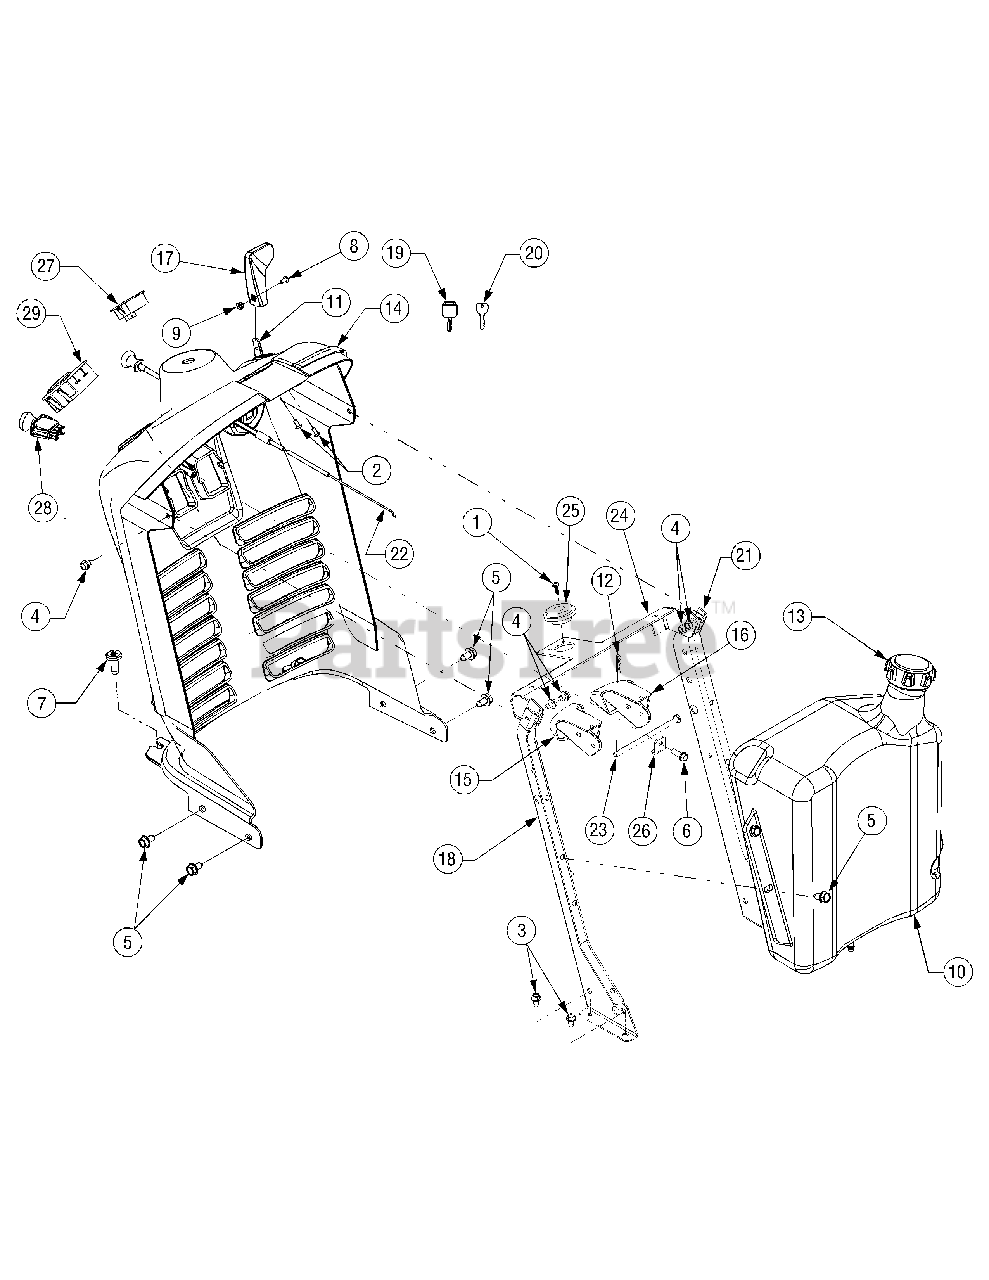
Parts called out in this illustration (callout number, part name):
1	Screw, #10-24 x .375
2	Screw, Pan Hd. #10-16 x .50
3	Screw, Self-tapping, 1/4-20, 0.5
4	Screw, Self-tapping. 1/4-20 x .375
5	Screw, Hex Tapp, 5/16-12 x .75
6	Screw, 1/4-15, 0.750
7	Screw, Torx Hd. , 5/16-18 x .75
8	Screw, Machine, #8-32, 0.375,
9	Nut, 8-32
10	Fuel Tank, 3 Gal
11	Control, Throttle, 27.4
12	Internal Cotter Pin, .072 x 1.13
13	Cap, Fuel
14	Dash
15	Lever, Dash, Cruise
16	Lever, Dash, Brake
17	Knob, Throttle Control
20	Ignition Key, Metal
22	Control, Choke, 24.0
23	Rod, .250 Dia x 4.25 Lg.
27	Monitor, Systems Indicator / Hour
28	Switch, PTO (Yellow Knob)
29	Switch Module, Ignition
